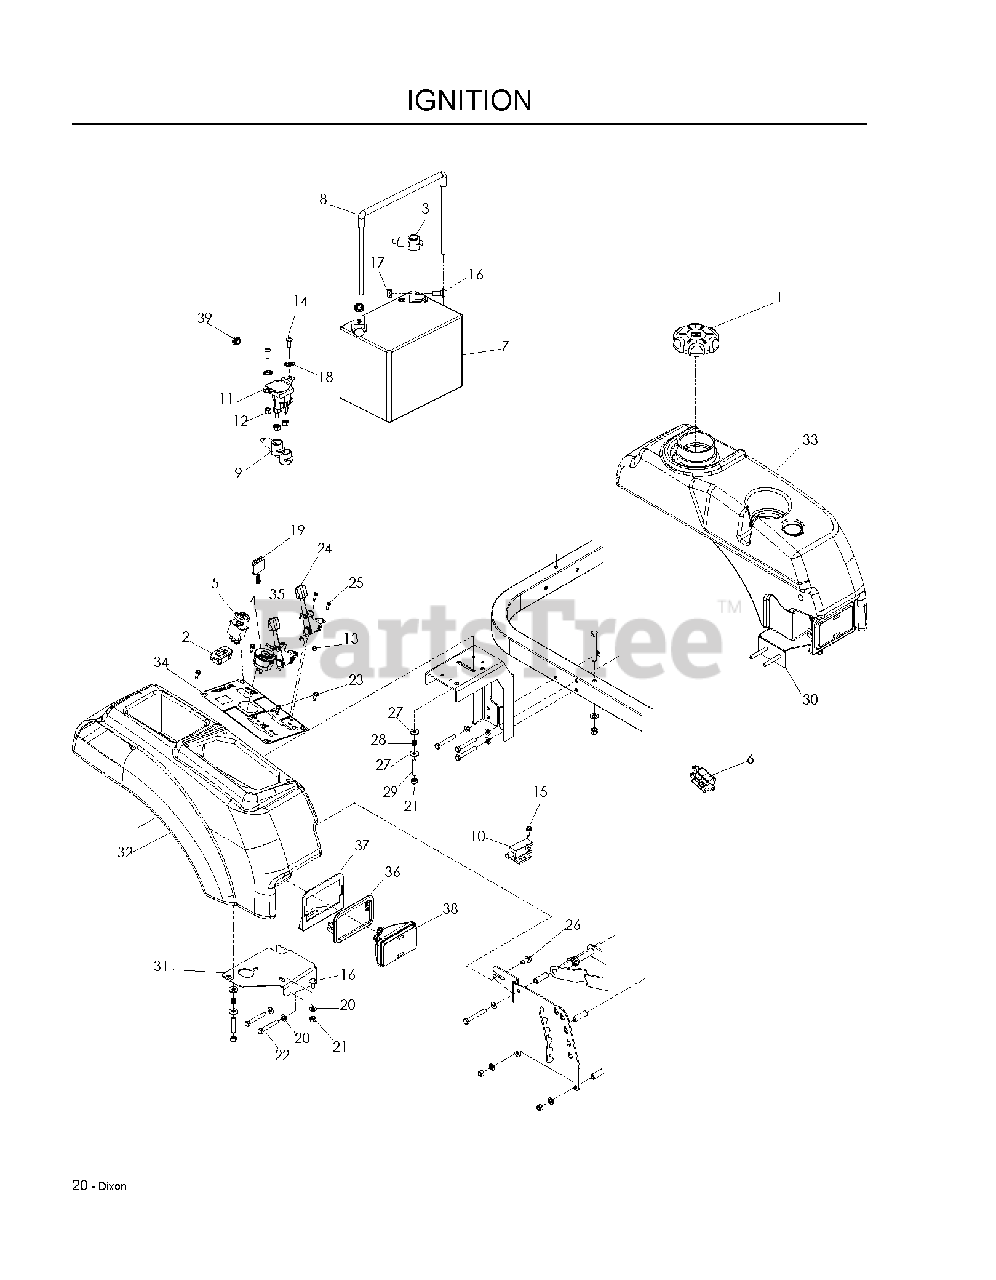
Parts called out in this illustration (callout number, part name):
2	HOUR METER
4	IGNITION SWITCH
5	SWITCH, BLADE
6	SWITCH, BRAKE 3P
7	BATTERY, 12 V 330 AMP TBR
8	BATTERY TIE DOWN ASSEMBLY
9	TERMINAL COVER-SM
10	SWITCH, INTERLOCK
11	SOLENOID
12	NUT 1/4-20 NYLOC
13	NUT 10-24 NYLOC
14	SCR 1/4-20 X 5/8 BTN SKT HD ZD
15	SCREW #10 X 1/2 SELF TAPPING
16	BOLT 5/16C X 3/4" CARRIAGE
17	5/16-18 NYLOC FLANGE NUT
18	WASHER 1/4 INT TOOTH
19	KEY
20	FLAT WASHER 5/16 SAE
21	NUT 5/16 NYLOC
22	CAPSCREW
23	SCREW 1/4 X 5/8
24	THROTTLE
25	SCREW #10-24 X 5/8
26	BOLT 5/16-18 X 3/4
27	WASHER 5/16 FLAT
29	STUD, 5/16C
30	SUPPORT, RAM TANK, LT BLK
31	SUPPORT, RAM TANK, RT BLK
32	FENDER-RH
33	FUEL TANK ASM.
34	DECAL, CONTROL PANEL RAM
35	CHOKE CABLE
36	HEADLIGHT BEZEL
37	BRACKET HEADLIGHT.
39	JAM NUT 1/4C
